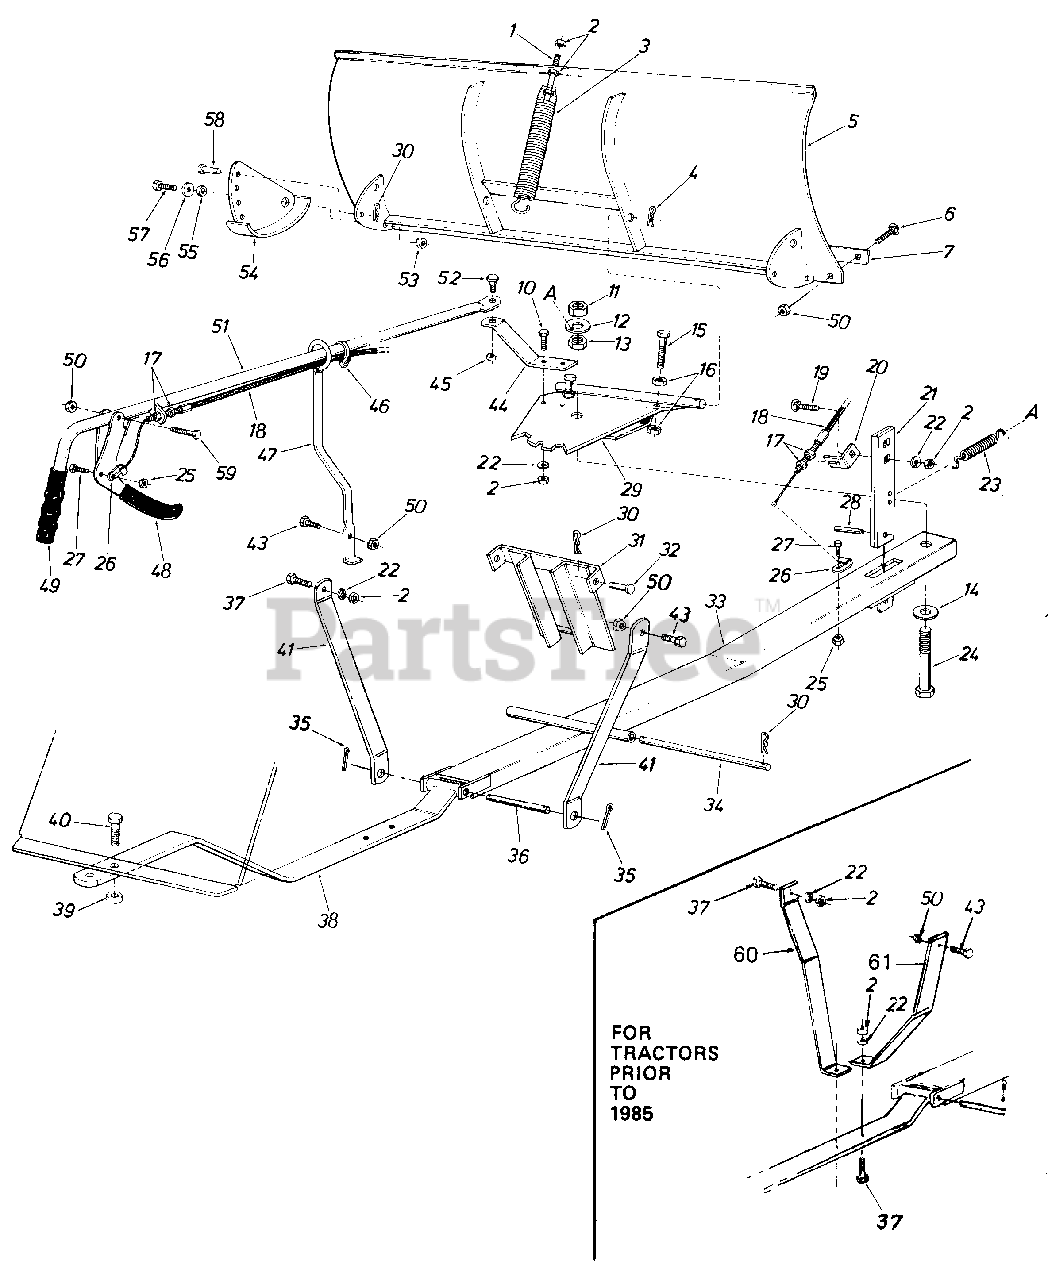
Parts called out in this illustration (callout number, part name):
1	Hex Scr. 3/8-16 x 4.50" Lg.
2	Hex Nut 3/8-16 Thd.
3	Blade Adjustment Spring
4	Hair Pin Cotter 5/32" Dia.
5	48" Blade Ass'y.
6	Carriage Bolt 5/16 18 x.75" Lg.
7	Wear Plate 48"
10	Hex Scr. 3/8 16 x 1.00" Lg.
11	Hex L. Nut 3/4 10 Thd.
12	Fl. Wash. .810" I.D. x 2.00" O.D.
13	Hex Jam Nut 3/410 Thd.
14	Fl. Wash. .810" I.D. x 2.00" O.D.
15	Hex Scr. 1 /2-13 x 2.00" Lg.
16	Hex Nut 1/2-13 Thd.
17	Hex Jam Nut 5/16 24 Thd.
18	Control Cable Ass'y.
19	Carriage Bolt 3/8-16 x 1.25" Lg.
20	Cable Guide Bracket
21	Angle - Lock Bar
22	L. Wash. 3/8" Scr.
23	Angle Lock Spring
24	Hex Scr. 3/4 10 x 4.00" Lg.
25	Hex L. Nut 1/4 20 Thd.
26	Clevis Lanyard Fitting
27	Hex Scr. 1/4 20 x .75" Lg.
28	Spring Pin Spirol 1/4 " Dia. x 1.00"
29	Pivot Plate Ass'y.
30	Hair Pin Cotter 3/32" Dia.
31	Guide Bracket Ass'y.
32	Clevis Pin 1/2" Dia. x 1 00" Lg.
33	Push BarAss'y.
34	Lift Shaft
35	Cotter Pin 5/32" Dia. x 1.00" Lg.
36	Pivot Pin
37	Hex Scr. 3/8 16 x 1.25" Lg.
38	H anger B racket Ass'y .
39	Hex L. Nut 5/8-11 Thd.
40	Hex Sc;. 5/8-11 x 1.50" Lg.
41	Hanger Link
43	Hex 5/16-18 x 1.00" Lg.
44	Blade Pivot Bracket
45	Hex Jam Nut 3/8 16 Thd.
46	Nylon Cable Tie
47	Tube Guide Ass'y.
48	Clutch Grip Ass'y.
49	Grip 3/4' Handle
50	Hex L Nut 5/16-18 Thd.
51	Tube Handle Ass'y.
52	Shld. Scr. Special 3/8-16 Thd.
53	Hex L. Nut 3/8-16 Thd.
54	Skid Assembly
55	Spacer
56	Fl.-Wash. .385" I.D. x 1.00" O.D.
57	Hex Scr. 3/8-16 x .75" Lg.
58	Clevis Pin 5/16" Dia. x.75" Lg.
59	Hex Scr. 5/16 18 x 1.50" Lg.
60	Mounting Brkt. L.H.
61	Mounting Brkt. R.H.
